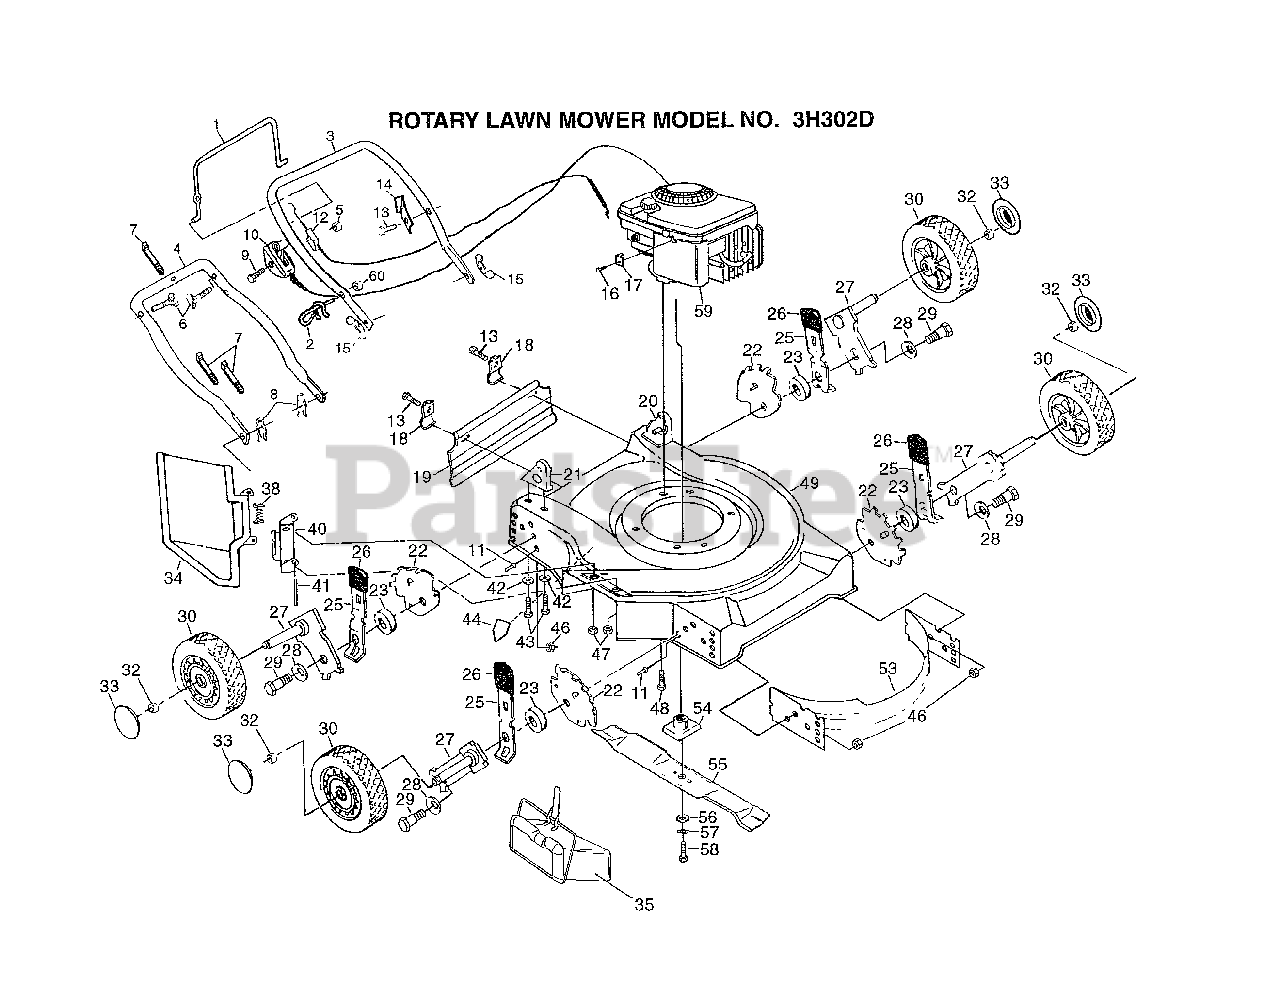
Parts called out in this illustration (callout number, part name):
1	CONTROL BAR
2	ROPE GUIDE
6	BOLT.HANDLE.LM
8	HAIRPIN COTTER
9	SCREW.HXHD.WASH.
10	"CONTROL, THROTTLE"
11	BLIND RIVET
12	"CABLE,ENG ZONE CO"
13	TAPPING SCREW
14	"BRKT,UPSTOP"
15	"NUT,WING PM"
16	SCREW PM
17	CABLE CLAMP
18	"BRKT,DEFL PM"
19	SKIRT.REAR.FGD.22
22	BRACKET.ADJ.9POS.
25	SPRING SELECTOR
26	KNOB PM
27	ARM.AXLE.ASM.BZP.
28	"WASHER, BELLEVIL."
29	BOLT SHLD 3/8-16
30	WHEEL.8X1.75.WHT
32	HEX FLANGE LOCKNT
33	HUB CAP
34	GUARD.DISCH.22SD.
35	PLUG.MULCHING.ASM
37	LOCKNUT
40	BRACKET.HINGE.W/F
41	ROD.HINGE.COMBI-C
42	STEEL WASHER
43	SCREW
44	DECAL HYT
46	LOCKNUT PM
48	SCREW
49	KIT.HSG.22SD.PUSH
53	BAFFLE.FRT/REAR
54	BLADE ADAPTOR
55	"BLADE.MULCH.22"""
56	"WASHER,HARDEN"
58	SCREW
60	NUT
67	LOCKWASHER
